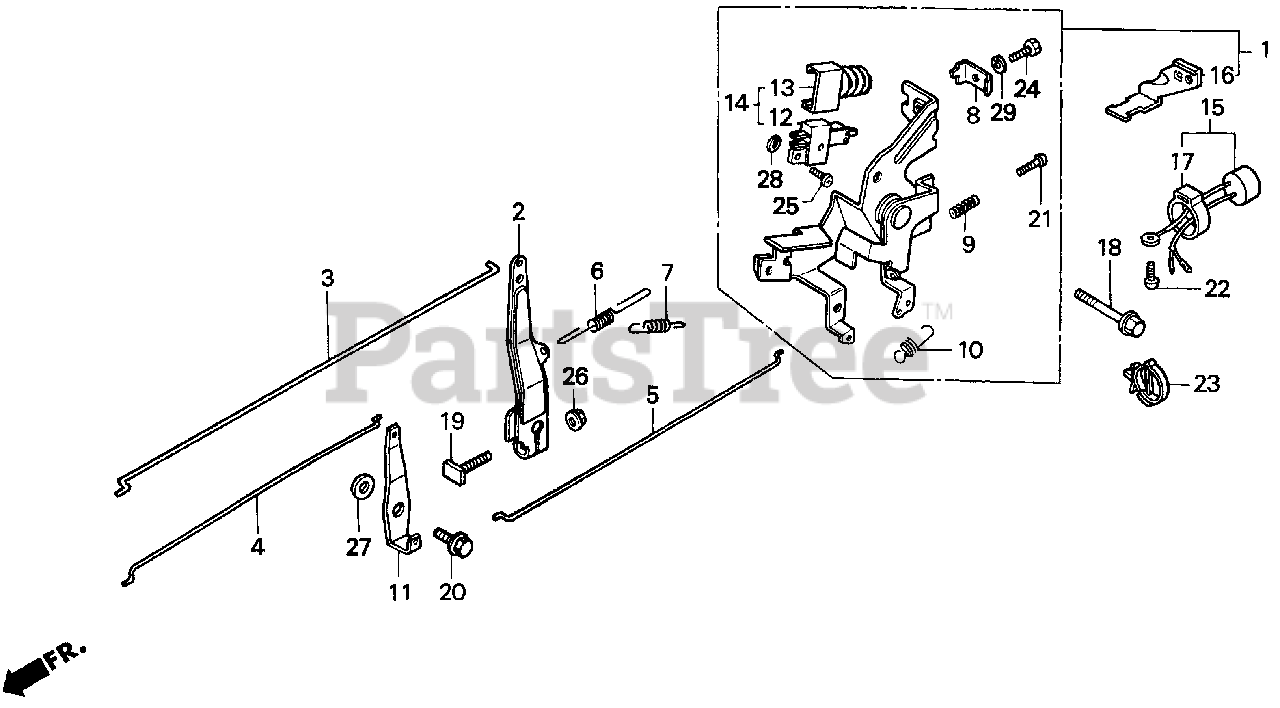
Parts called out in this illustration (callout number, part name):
1	CONTROL ASSY.
2	ARM, GOVERNOR
3	ROD, GOVERNOR
4	ROD, CHOKE
5	ROD, JOINT
6	SPRING, GOVERNOR
7	SPRING, GOVERNOR PRIMARY
8	HOLDER, CABLE
9	SPRING, CONTROL ADJUSTING
10	SPRING, CABLE RETURN
11	LEVER, CHOKE JOINT
12	SWITCH ASSY., ENGINE
13	COVER, SWITCH
14	SWITCH ASSY., ENGINE STOP
18	BOLT, FLANGE (6X12) (CT200)
19	BOLT, GOVERNOR ARM
20	BOLT, FLANGE (6MM)
21	SCREW, PAN (5X20)
24	BOLT, SLOT (5X14)
25	SCREW, PAN (4X14)
26	NUT, FLANGE (6MM)
27	WASHER, PLAIN (6MM)
28	WASHER, SPRING (4MM)
